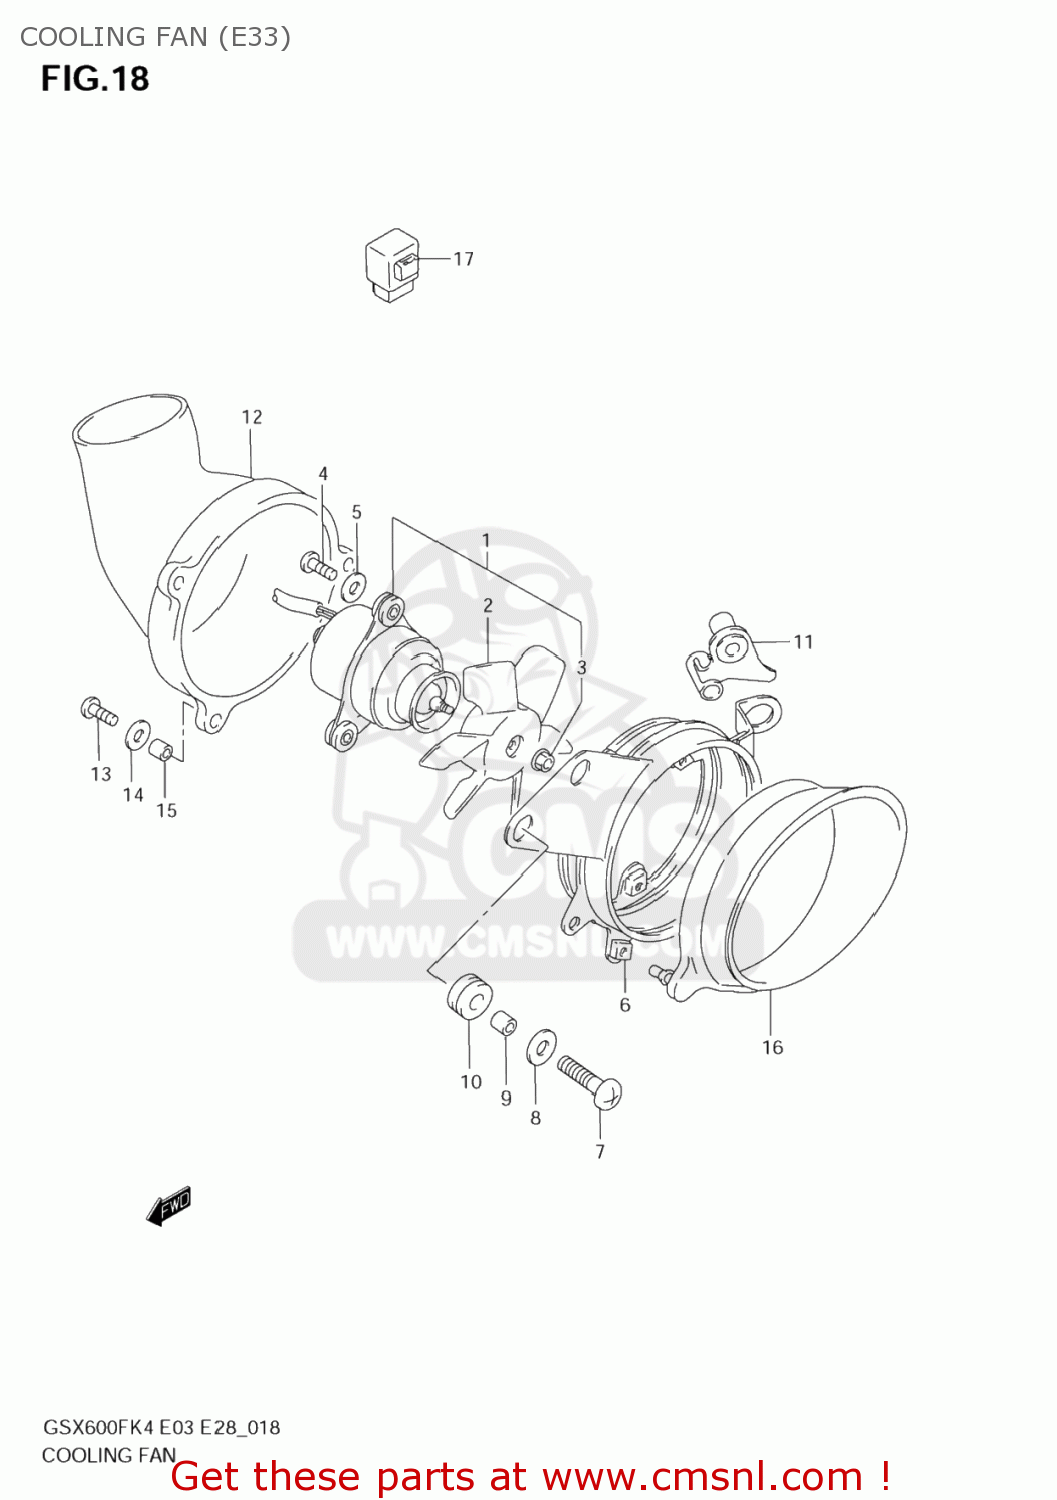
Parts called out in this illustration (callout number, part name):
1	FAN ASSY,COOLING
2	FAN
3	NUT
4	SCREW 4X16
5	WASHER(4.3X14X0.8)
6	SHROUD,FAN
7	SCREW
8	WASHER(6.5X18X1)
9	SPACER(6.5X9X6.5)
10	CUSHION
11	BRACKET,FAN SHROUD
12	DUCT,FAN COOLING NO.1
13	SCREW
14	WASHER(4.3X14X0.8)
15	SPACER(4.5X6.5X5)
16	DUCT,FAN COOLING NO.2
17	CONTROLLER ASSY,FAN MOTOR
